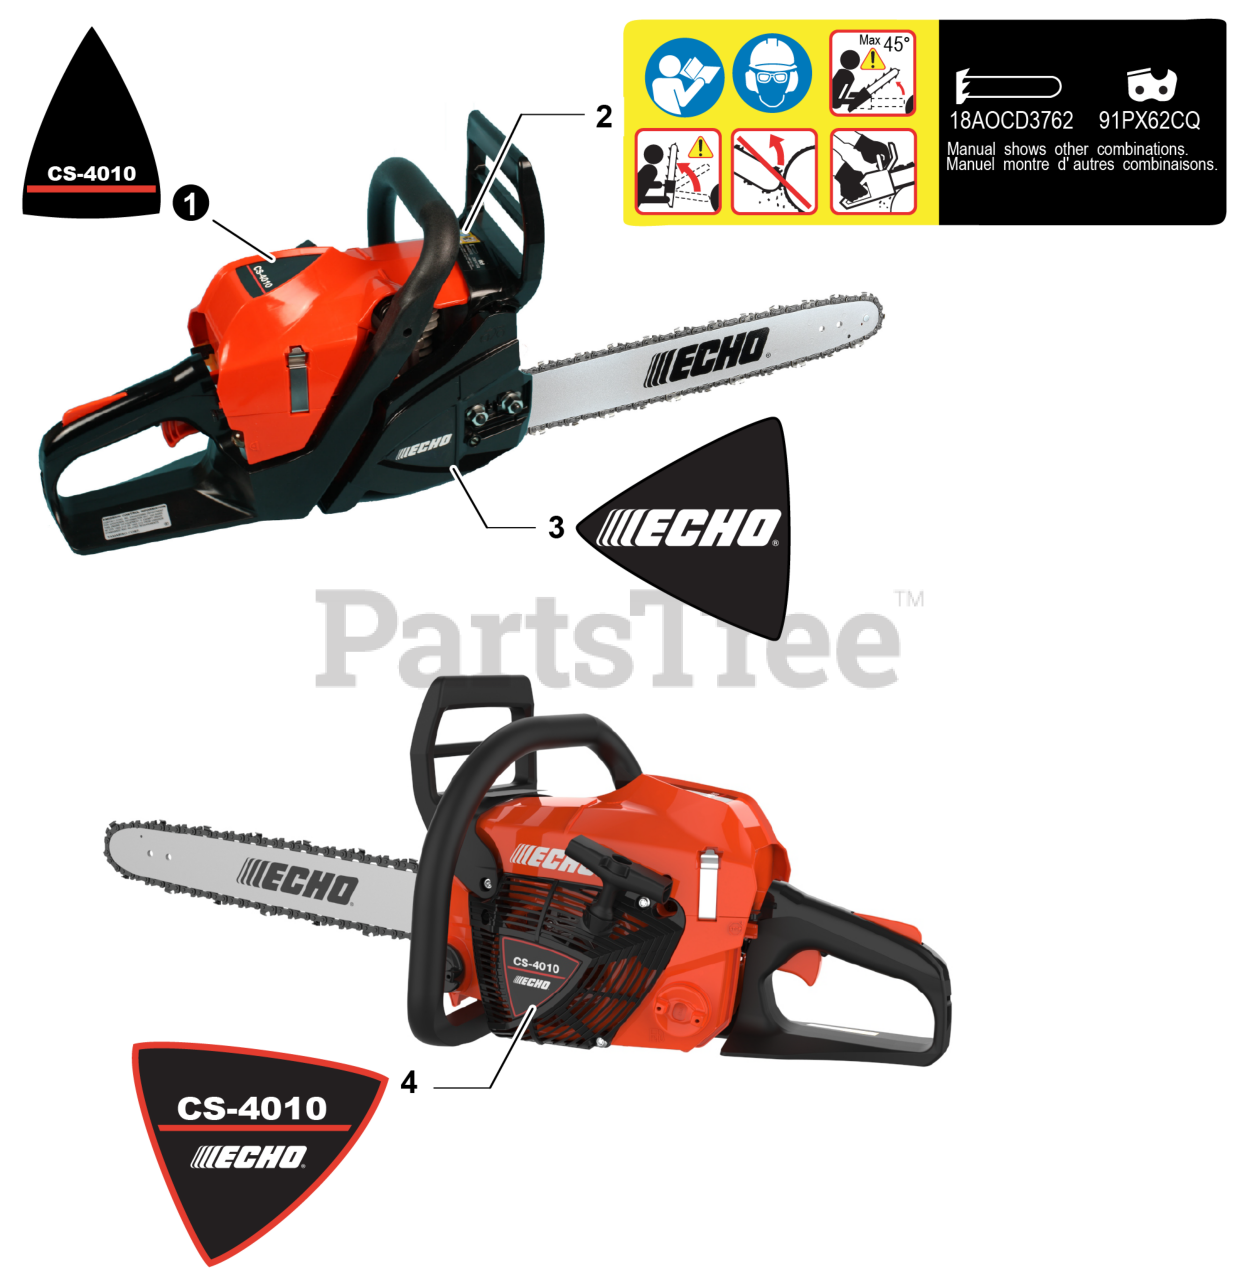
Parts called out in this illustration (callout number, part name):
1	LABEL - CS-4010
2	LABEL - CAUTION
3	LABEL - ECHO
4	LABEL - STARTER - CS-4010
